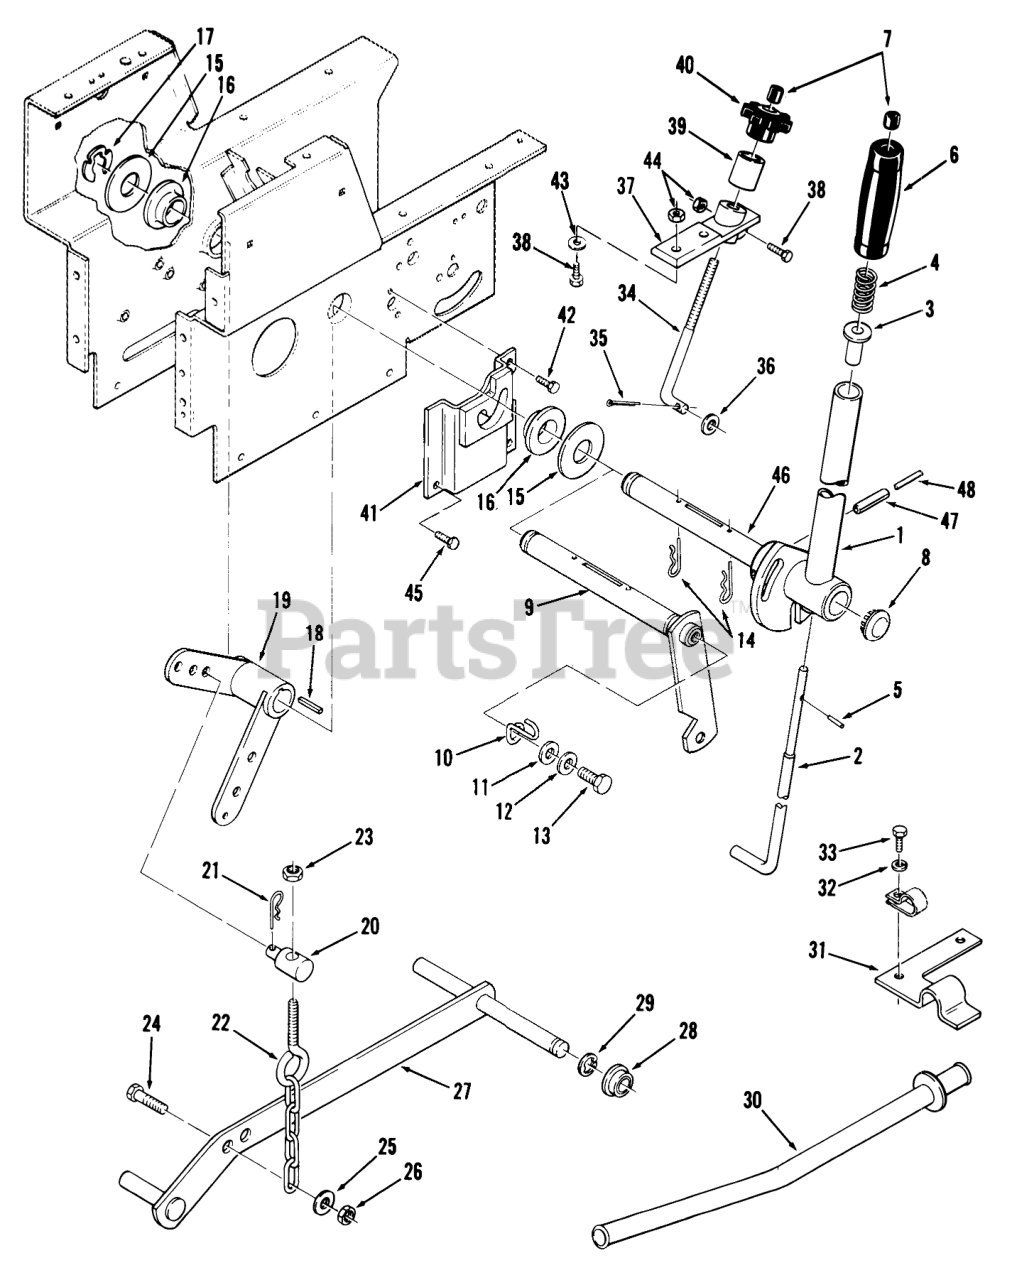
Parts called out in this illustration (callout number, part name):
1	Lift Lever
2	ROD-LATCH LIFT
3	RETAINER-SPRING
4	SPRING-COMPRESSION
5	PIN-SPIROL
6	HANDGRIP
7	CAP-ROD, PLUNGER
8	PLUG
9	Lift Lever
10	Indicator
11	WASHER 5/16 SAE
12	Lockwasher
13	Screw
14	Pin-Cotter
15	WASHER
16	BEARING-FLANGE
17	Retainer
18	KEY-SQUARE
19	Bellcrank
20	TRUNNION-LIFT
21	Hairpin
22	CHAIN-LIFT
23	Nut
24	Bolt
25	WASHER 5/16 SAE
